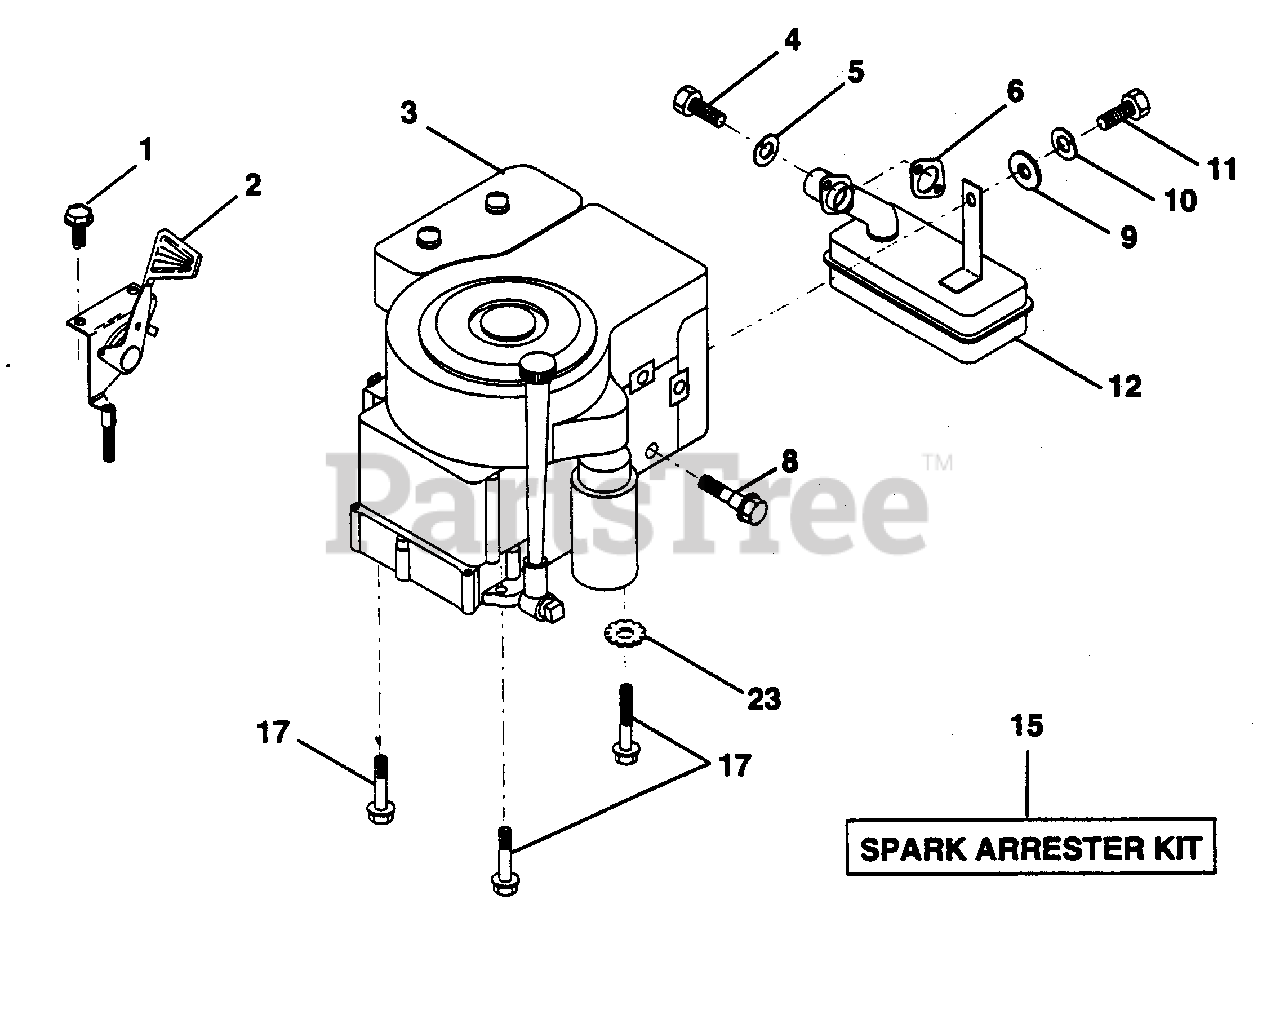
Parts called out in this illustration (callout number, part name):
1	Screw, Hex Thd. Cut 1/4-20 x 1/2 (AYP part number)
2	Control, Throttle (AYP part number)
4	Screw, Hex, Cap 5/16-18 x 3/4 (AYP part number)
5	Washer, Lock Heavy Helical Spring 5/16 (AYP part number)
6	Gasket, Exhaust (AYP part number)
8	Bolt, Shoulder 5/16 (AYP part number)
9	Washer 5/16 x 3/4 x 16 (AYP part number)
10	Washer, Lock Hvy Hlcl Spring 1/4 (AYP part number)
12	Muffler (AYP part number)
15	Arrester, Spark (Optional equipment) (AYP part number)
17	Screw, Hex Washer Head, Thdrol. 3/8-16 x 1-1/2 (AYP part number)
23	Washer, Lock Ext. Tooth 3/8 (AYP part number)
